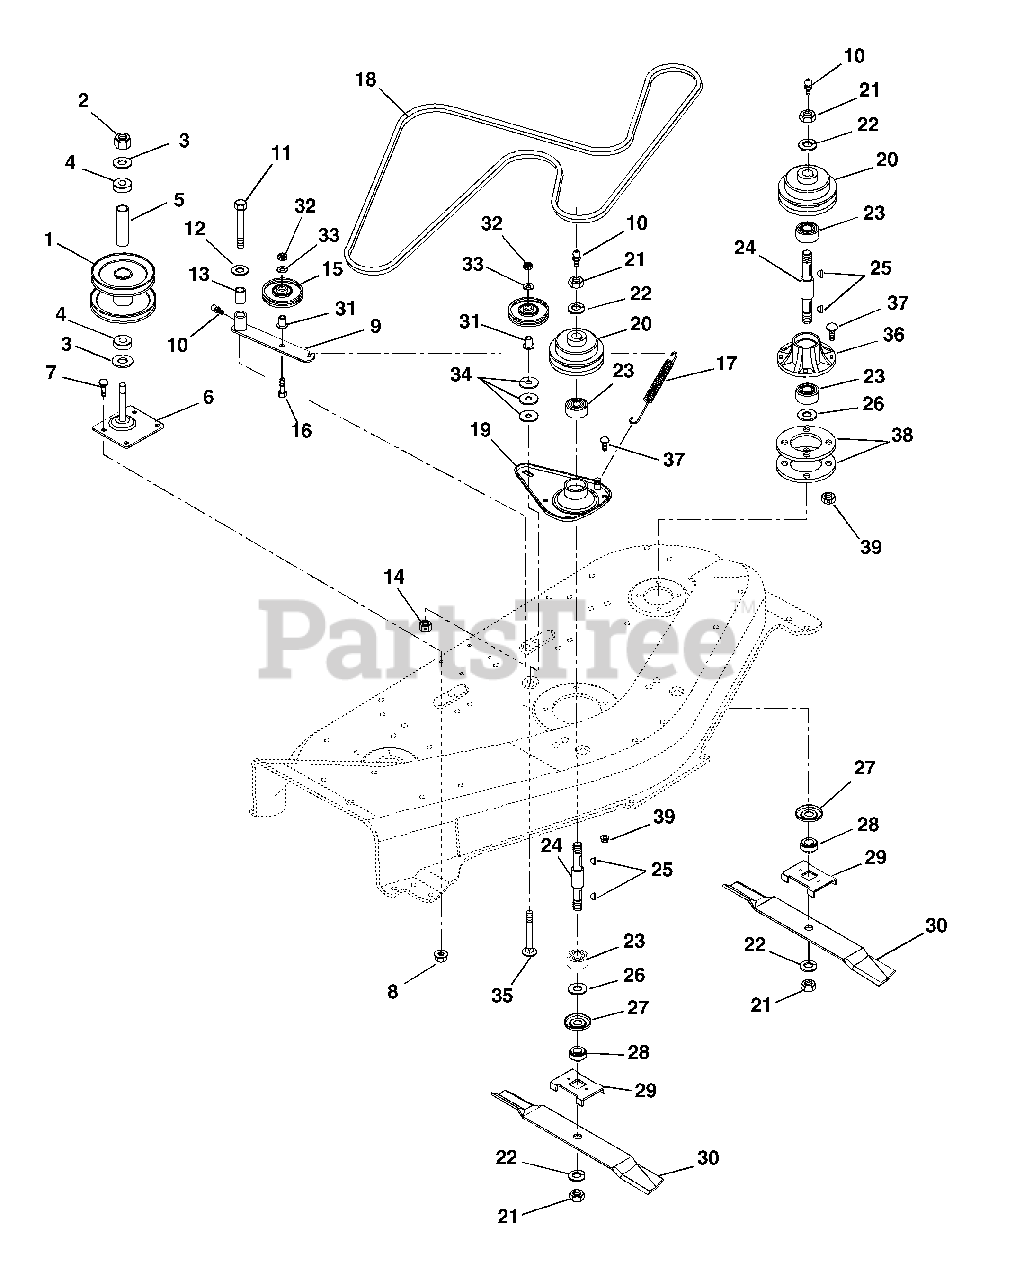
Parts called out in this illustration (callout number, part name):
1	JACKSHAFT - 48" DECK
2	@NUT-LK-NYL .625-18 YWZC
3	WSHR-FL-STL .630X1.005X.062 YZ
4	BRG-BALL .625X1.375X.44
5	SPACER .640X.880X2.545
6	PLATE, MOUNT
7	@BLT-RDHDSQNK .31-18X.75 G5YZ
8	@NUT-SPNLK-FLG .312-18 YWZC
9	ARM, IDLER
10	FTG-LUBE .25-28X.256 YWZC
11	@BLT-HEX .50-13X2.75 GR5 YWZC
12	WSHR-FL-STL .505X.880X.072 YWZ
13	SPACER, PIVOT .500X.750X1.805
14	@NUT-LK-CTR .50-13 YWZC
15	IDLER, PLASTIC, 4.00 X .50 ID
16	@BLT-HEX .38-16X1.50 GR5 YWZC
17	SG-TENS .075X.75X2.25 WLD20.7
18	V-BELT, HA-RAW EDGE
19	HOUSING, SPINDLE
21	NUT-JAM .75-10 YWZC
22	@WSHR-LK .75X.188 REG YWZC
23	BRG-BALL .750X1.781X.61
24	SPINDLE SHAFT W/ZERK
25	KEY-WDRF .188X.625X.25 SAE 61
26	WSHR-FL-STL .754X1.000X.032 YZ
27	BEARING SLINGER
28	RETAINER HUB
29	BLADE TRAY 48
31	SPACER -FLANGED .390X.500X.781
32	@NUT-LK-CTR .38-16 YWZC
33	@WSHR-FL-STL.38X.875X.083 YWZC
34	WSHR-FL-STL .390X1.5X.125 YWZC
35	@BLT-RDHDSQNK .38-16X1.75 G5YZ
36	SPINDLE HOUSING
37	@BLT-RDHDSQNK .38-16X.75 G5YZ
38	SPACER, SPINDLE
39	@NUT-LK-TOP-FLG .38-16 YWZC
